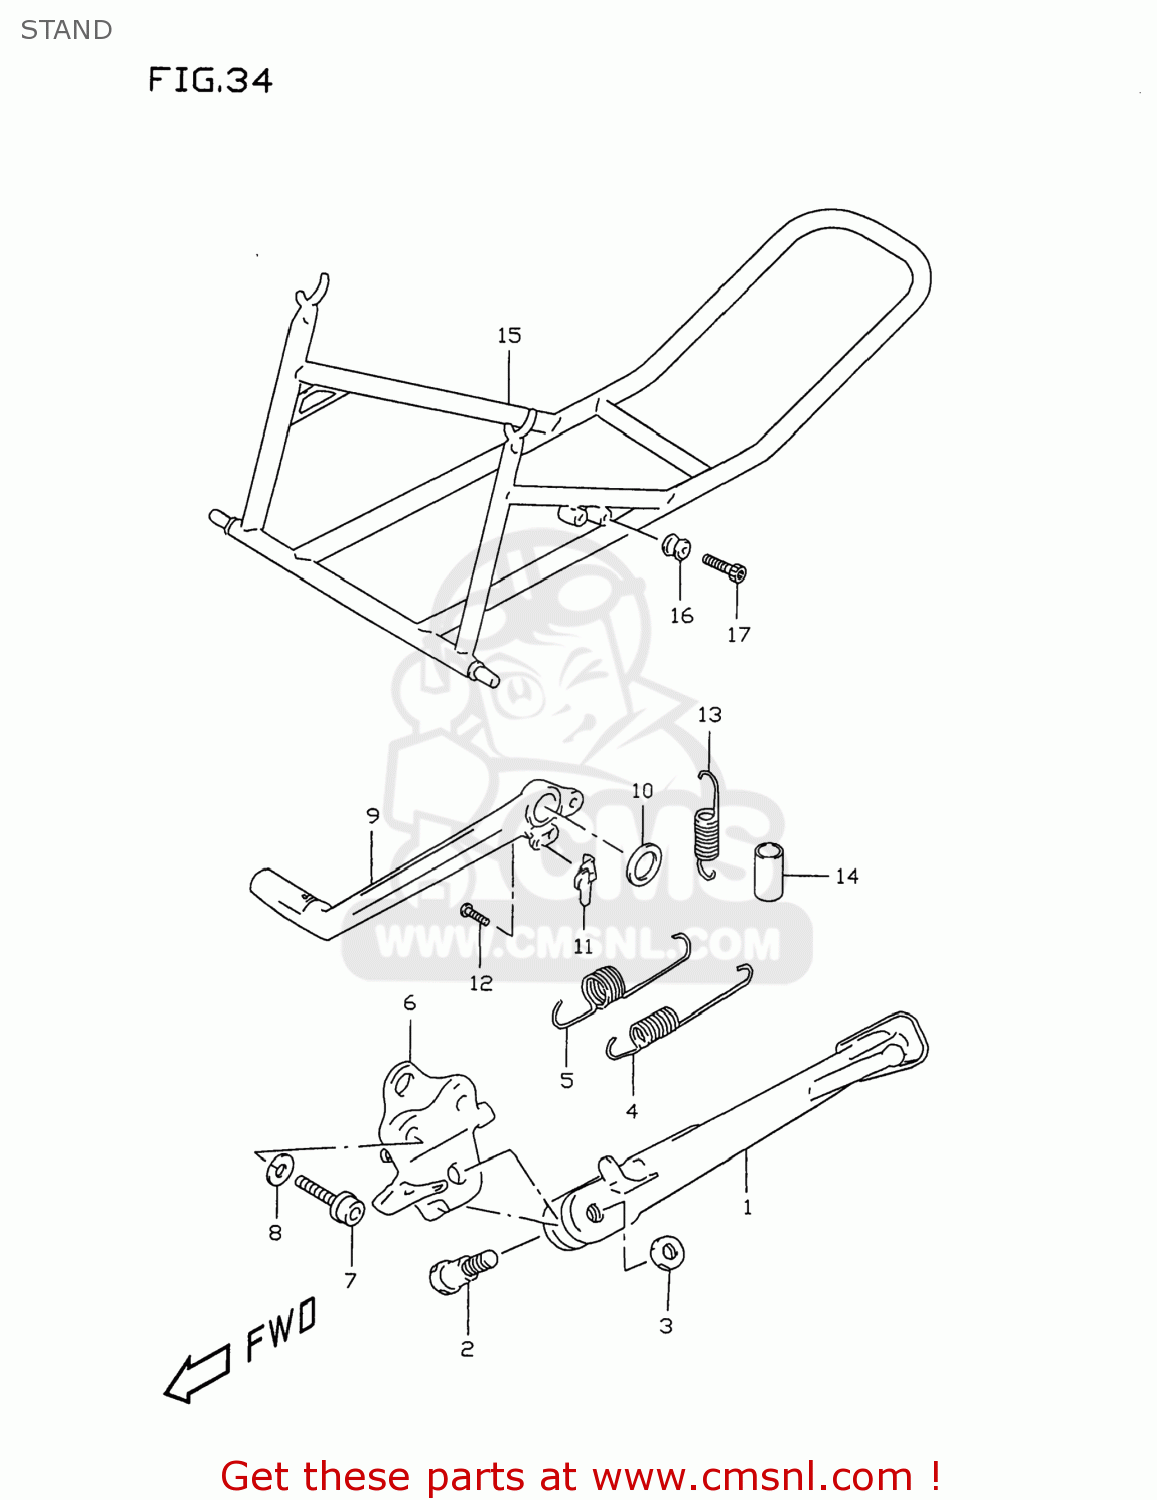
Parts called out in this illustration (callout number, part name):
1	STAND,PROP
2	BOLT(10X34)
3	NUT
4	SPRING
5	SPRING
6	BRACKET,PROP STAND
7	BOLT
8	LOCK WASHER
9	PEDAL,BRAKE
10	WASHER(18X24X1)
11	HOOK,RETURN SPRING
12	SCREW
13	SPRING
14	TUBE,BRAKE SPRING GUIDE
15	STAND ASSEMBLY,REAR
16	HOLDER,STAND
17	BOLT
